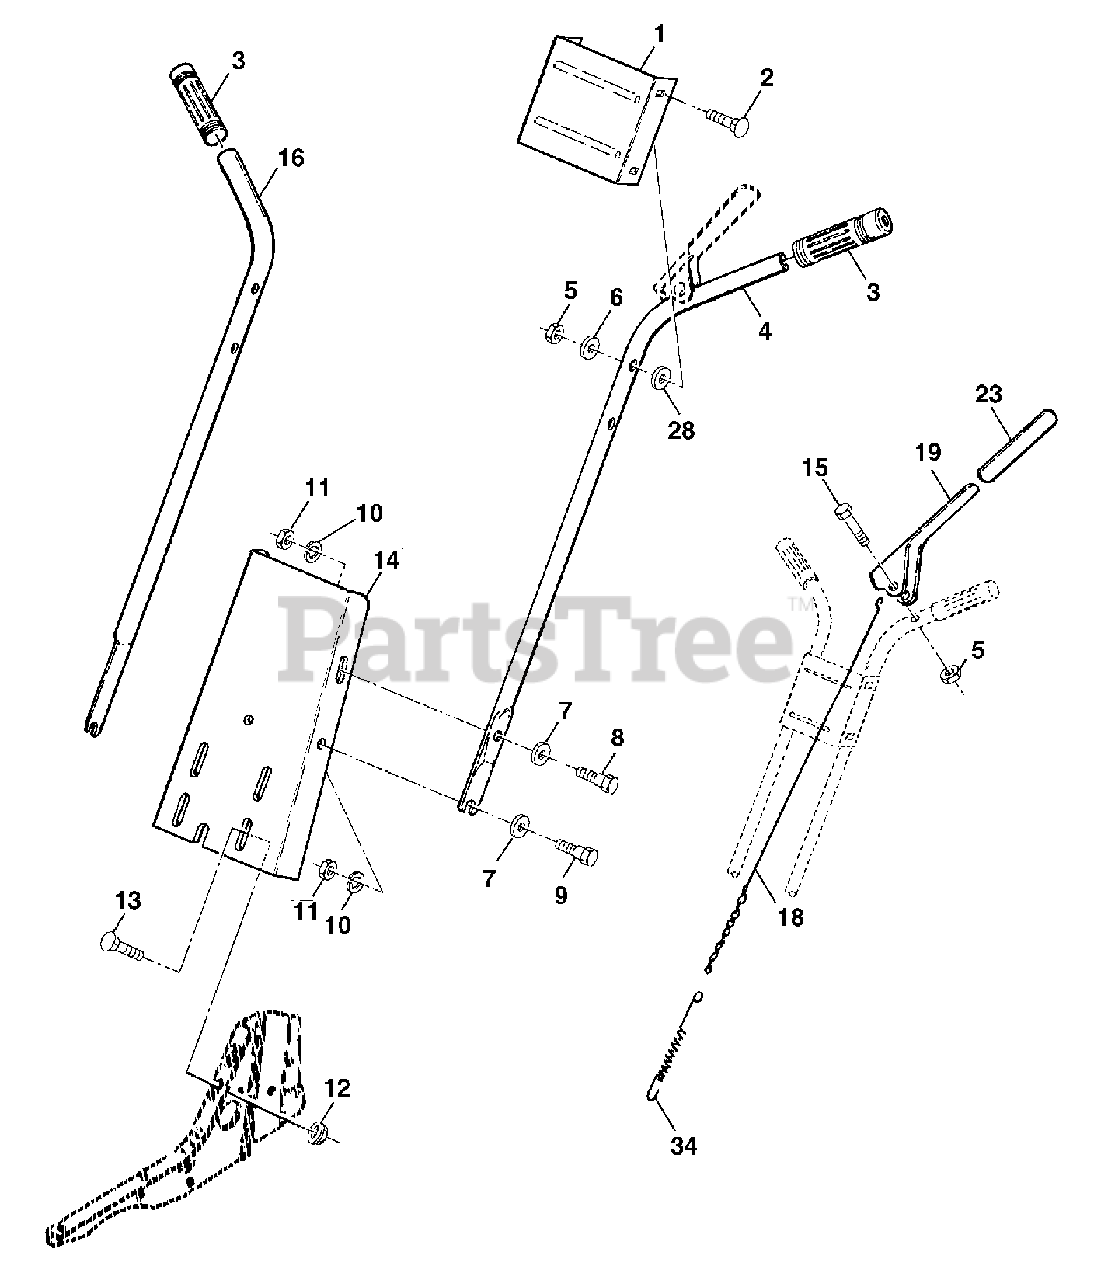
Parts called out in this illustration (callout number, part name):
1	Bracket, Handle
2	Bolt, Carriage 5/16-18 UNC x 1-1/2
3	Grip, Handle
4	Handle, L.H.
5	Locknut, Crown 5/16-18
6	Washer 11/32 x 11/16 x 16 Ga.
7	Washer 3/8 x 7/8 x 14 Ga.
8	Bolt, Hex Hd. 5/16-18 x 1
9	Bolt, Hex Hd 5/16-18 x 3/4
10	Washer, Lock 5/16
11	Nut, Hex 5/16-18
12	Nut, Flanged 5/16-18
13	Bolt, Carriage 5/16-18 x 3/4 Gr. 5
14	Panel, Handle
15	Bolt Fin Hex 5/16-18
16	Handle, R.H.
18	Cable Asm Clutch
19	Lever Clutch
23	Grip Handle
28	Washer 13/32 x 13/16 x 12 Ga.
34	Spring
